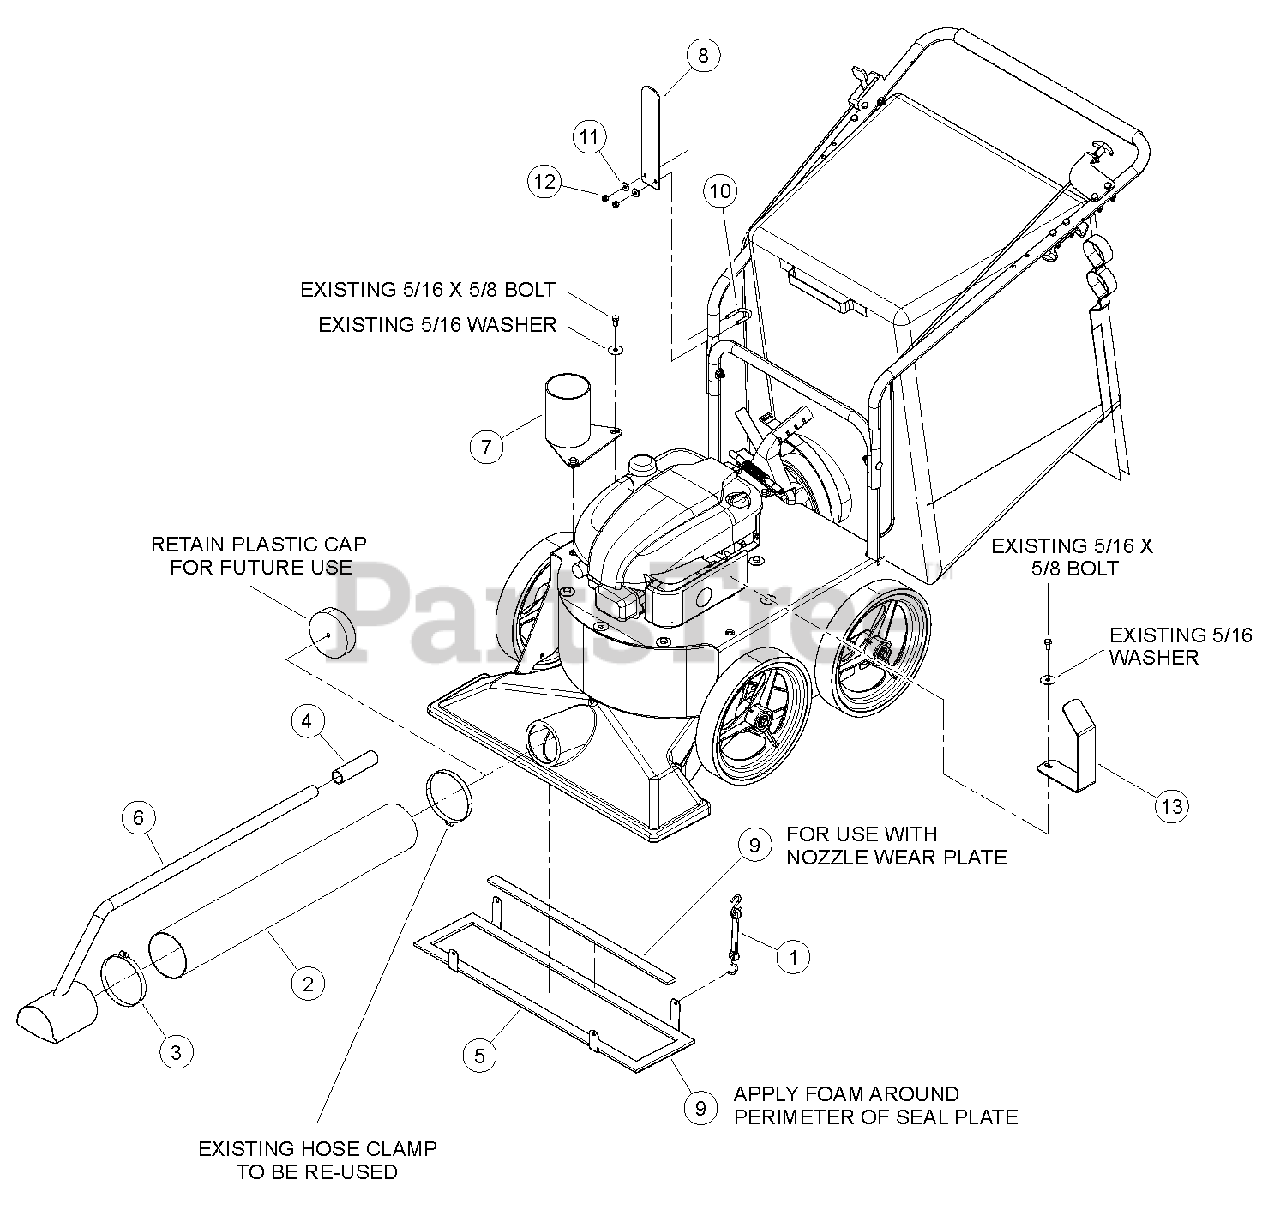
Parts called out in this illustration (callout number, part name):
1	STRAP, 6" TARP
2	HOSE, PVC 4" ID X 10' LG
3	CLAMP, 4" HOSE
4	GRIP, 1" ID X 4.63"
5	PLATE, BEAR VAC HOSE KIT SEAL
6	WELDMENT, 4" HOSE NOZZLE
7	WELDMENT, HOSE HOLDER/PLUG
8	STRIP, HOSE HANGER
9	FOAM, PLATE SEAL
10	U-BOLT, 1/4 X 1.0 X 1.75" ZP
11	WASHER, 1/4" FLAT ZP
12	LOCKNUT, 1/4" - 20 NYLON TYPE NE ZP
13	BRACKET, HOSE HOLDER
